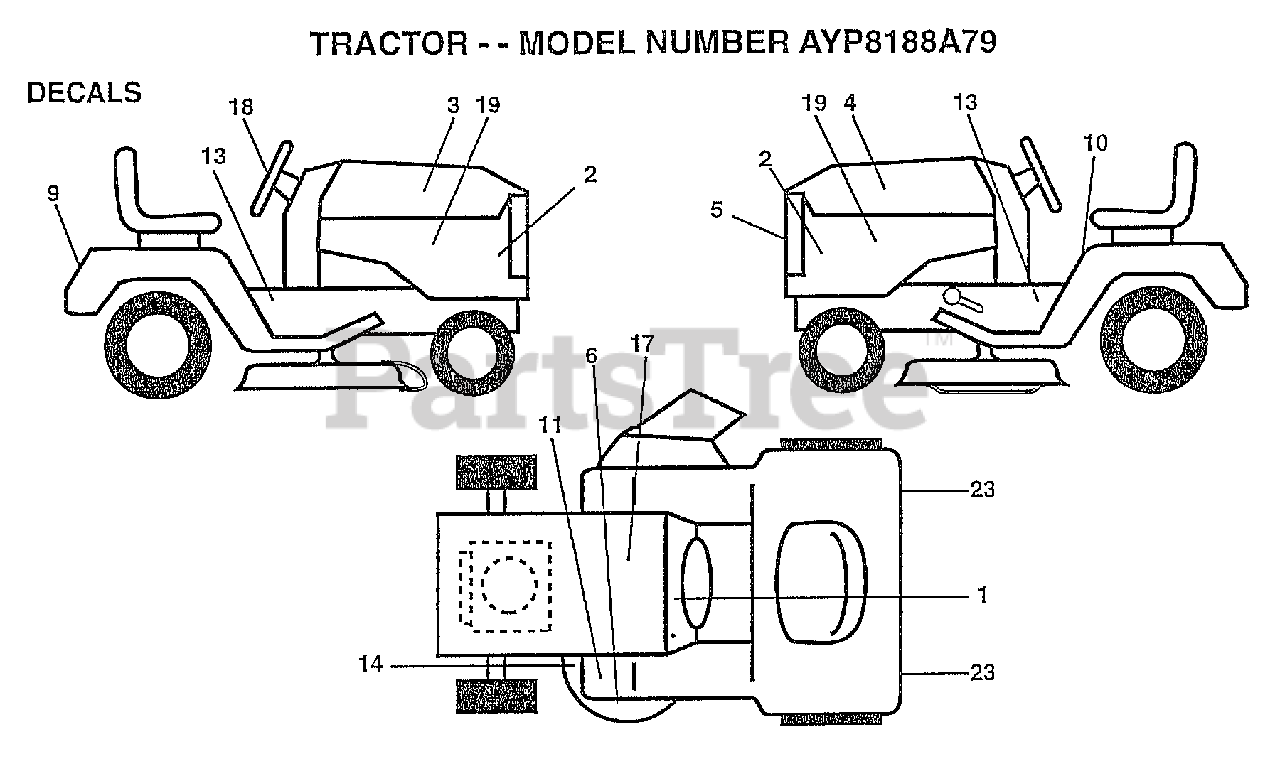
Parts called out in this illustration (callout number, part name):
1	"DECAL-OPER,GEAR D"
2	NAMEPLATE.HD.WIZA
3	DECAL.HD.RH.WIZRD
4	DECAL.HD.LH.WIZRD
5	DECAL.GRILLE.WIZ+
6	DECAL DECK WIZ +
10	"DECAL DANGER,FEND"
13	DECAL CHASSIS
14	"DECAL.V.BELT.44"""
17	DECAL.BATRY.3-3908
18	DECAL INS STG WHL
19	DECAL.PNL.SD.VANG
23	REFLECTOR-TAIL YT
